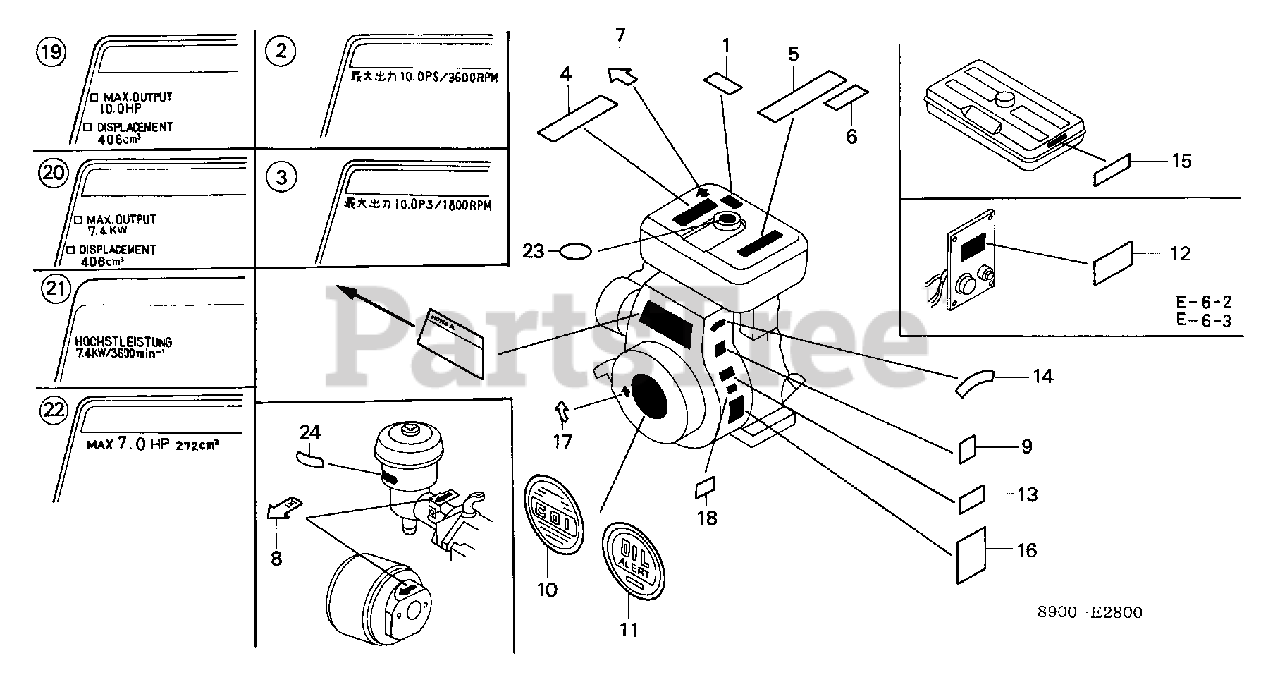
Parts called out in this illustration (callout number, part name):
4	MARK, CAUTION (ENGLISH/FRENCH/SPANISH)
8	MARK, CHOKE
10	MARK, C.D.I.
16	MARK, OIL CAUTION
17	MARK, STARTING (NOT AVAILABLE)
19	EMBLEM (ENGLISH/FRENCH/SPANISH)
